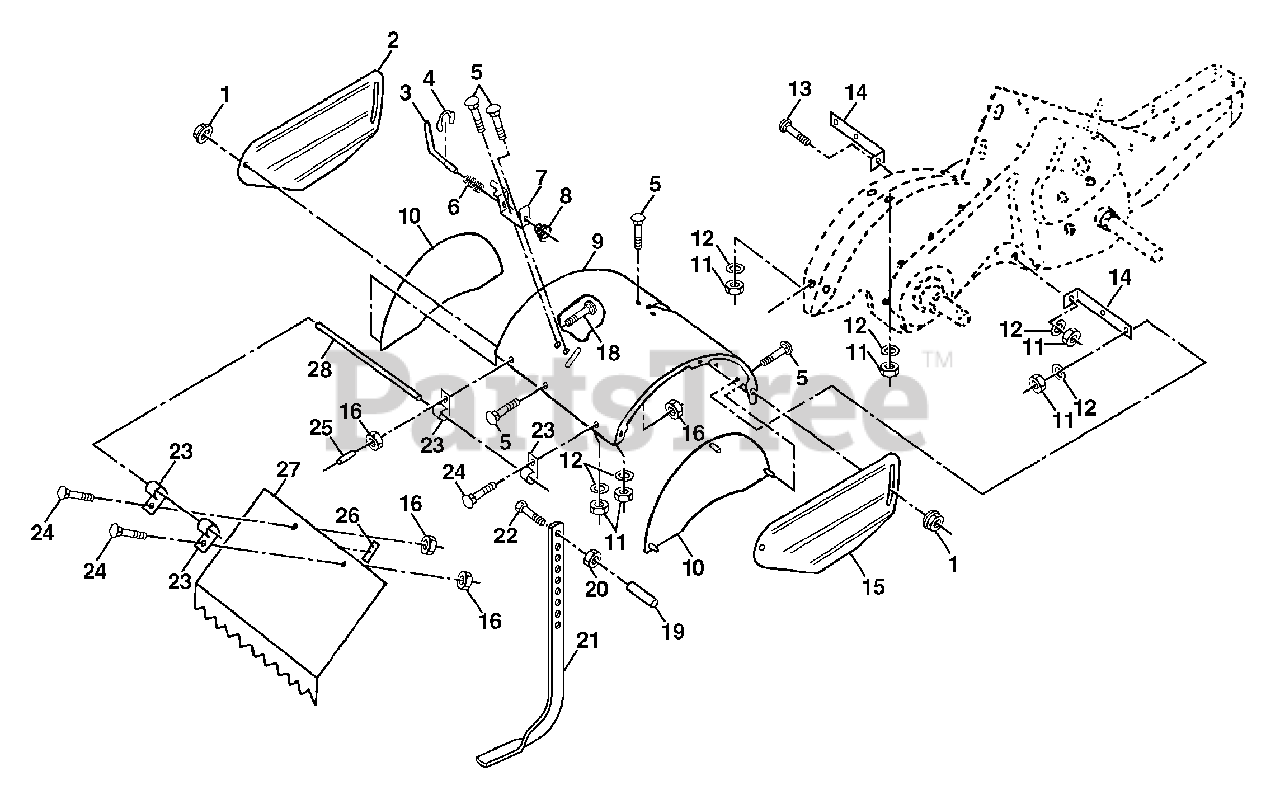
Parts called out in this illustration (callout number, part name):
1	Nut, Flange 5/16-18
2	Shield, Side, Outer L. H.
3	Pin, Stake, Depth
4	Ring, Klip
5	Bolt, Carriage 5/16-18 x 3/4 Gr. 5
7	Bracket, Latch
8	Spring, Depth Stake
9	Shield, Tine
10	Bolt, Carriage 5/16-18 UNC x 1
11	Nut, Hex 5/16-18
12	Washer, Lock 5/16
13	Bolt, Carriage 5/16-18 x 1-1/4
14	Bracket, Shield Tine
15	Shield, Side, Outer R.H.
16	Nut, Keps Hex 1/4-20
17	Washer, Lock 1/4
18	Bolt, Carriage 1/4-20 x 1-1/4 Gr. 5
20	Nut, Hex 3/8-16
21	Stake, Depth
22	Bolt, Hex 3/8-16 x 2
24	Bolt, Carriage 1/4-20 x 1/2 Gr. 5
25	Cap, Vinyl
26	Pad, Idler
27	Shield, Leveling
28	Pin, Hinge
29	Shield, Side
30	Locknut, Flange 5/16-18
